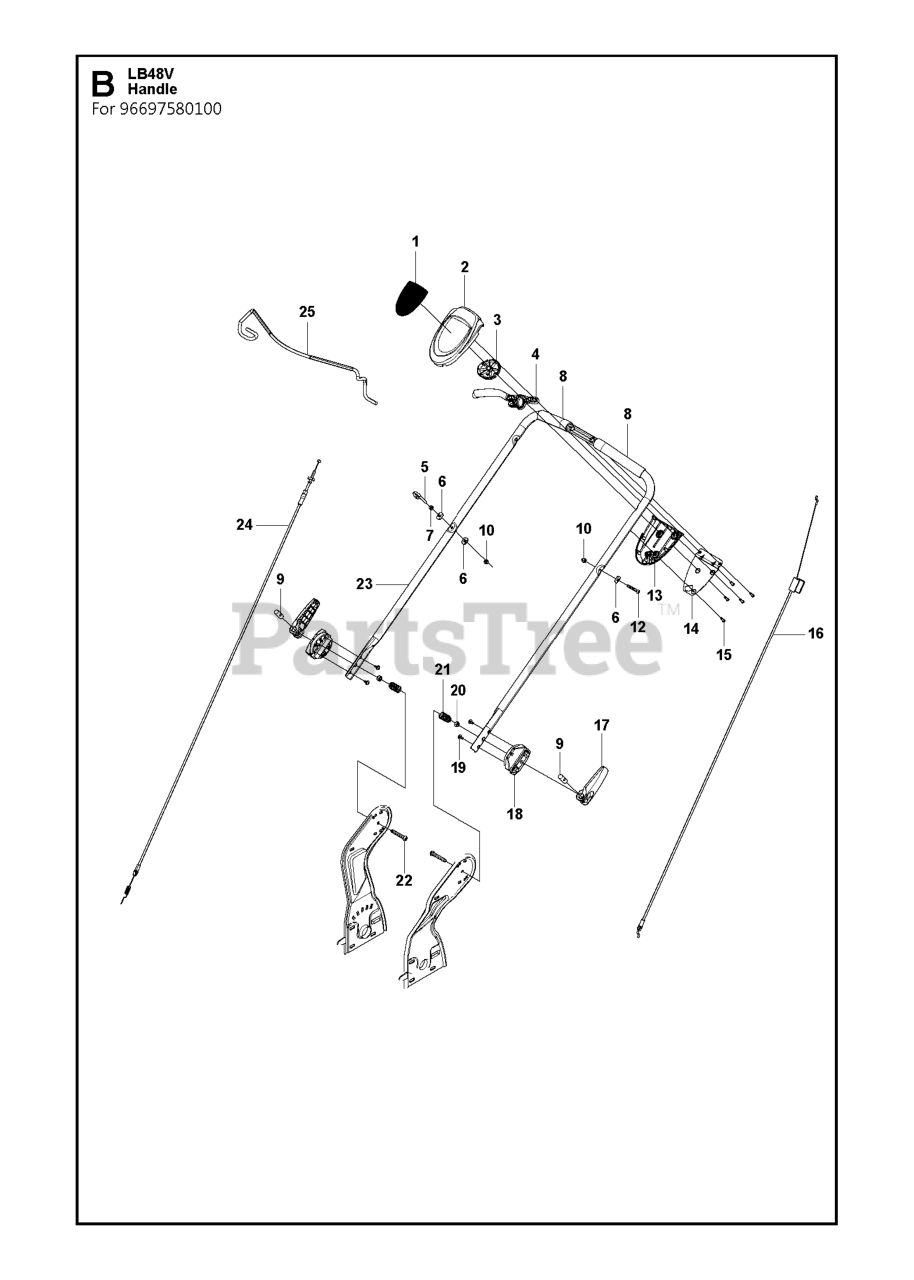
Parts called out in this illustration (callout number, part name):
2	COVER, DRIVE CONTROL BOTTOM
3	PULLEY.CAM.DRIVE.CONTROL.EZ
4	LEVER, DRIVE CONTROL
13	COVER, DRIVE CONTROL, TOP
14	BRACKET, DRIVE CONTROL
15	SCREW ITXPANT T50X16 ZN/FE (A
19	SCREW ITXPANTT M5X10 ZPB (A00
